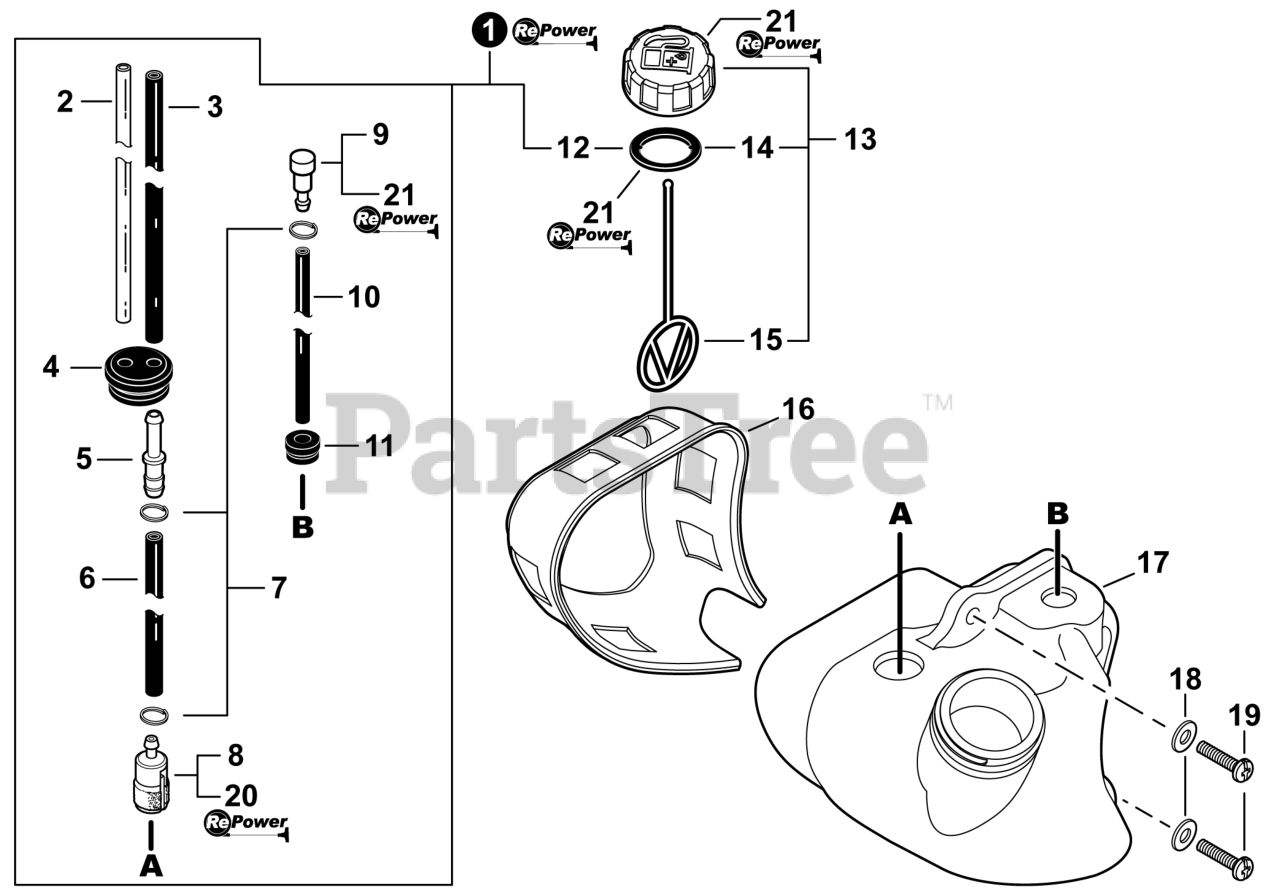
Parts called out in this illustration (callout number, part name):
1	FUEL SYSTEM KIT
2	PIPE, FUEL 3×6×85 CLEAR
3	PIPE, FUEL 3×5.5×87 BLACK
4	GROMMET, FUEL
5	CONNECTOR, PIPE Ø5ר3.5
6	PIPE, FUEL 3×5×90 BLACK
7	CLIP Ø6
8	FILTER, FUEL
9	VENT ASSY
10	PIPE, FUEL VENT 3×5×50
11	GROMMET
12	GASKET, FUEL CAP
13	CAP ASSY, FUEL
14	GASKET, FUEL CAP
15	CONNECTOR, CAP L= 100 MM
16	GUARD, FUEL TANK
17	FUEL TANK, PB-255LN (2020)
18	WASHER 5.5×12×0.8
19	SCREW, TAPPING 5×20
20	TUNE-UP KIT - REPOWER
21	CAP/VENT KIT - REPOWER
